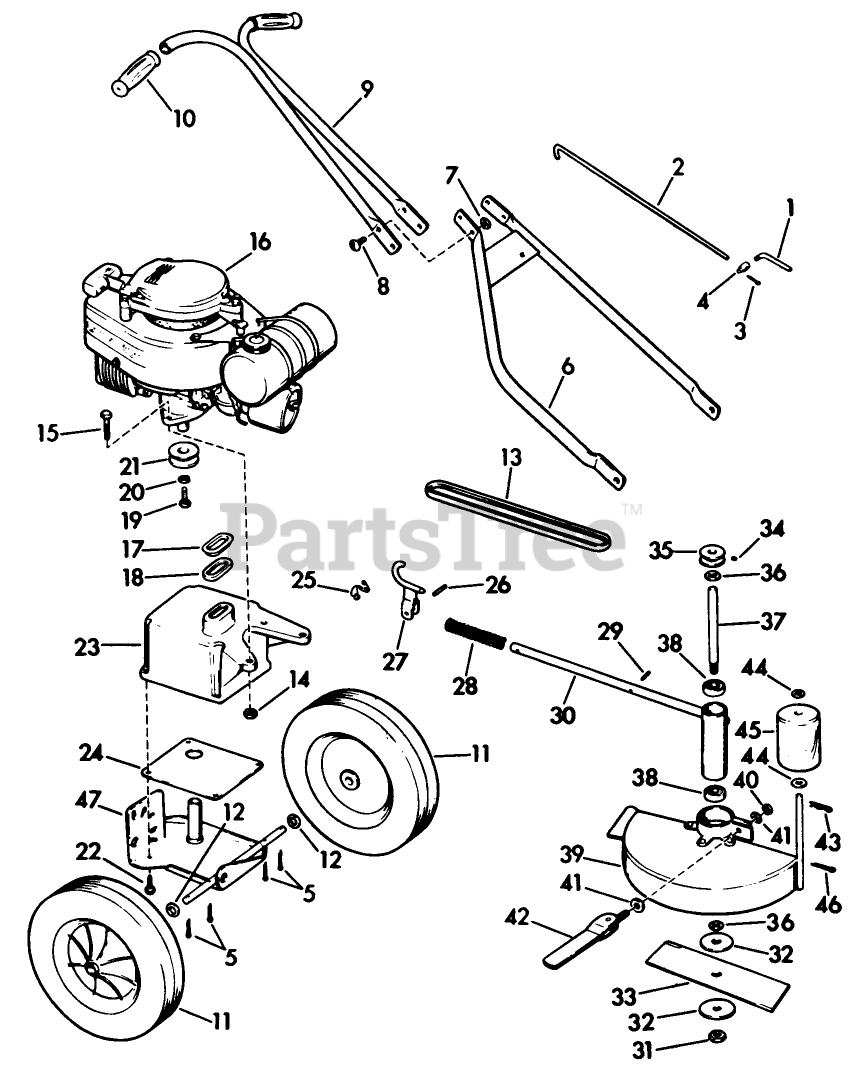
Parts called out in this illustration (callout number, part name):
3	Pin-Cotter
7	STOP NUT
16	Engine-C-71
20	WASHER, LOCK
33	Blade-9"
45	Roller-Wood
